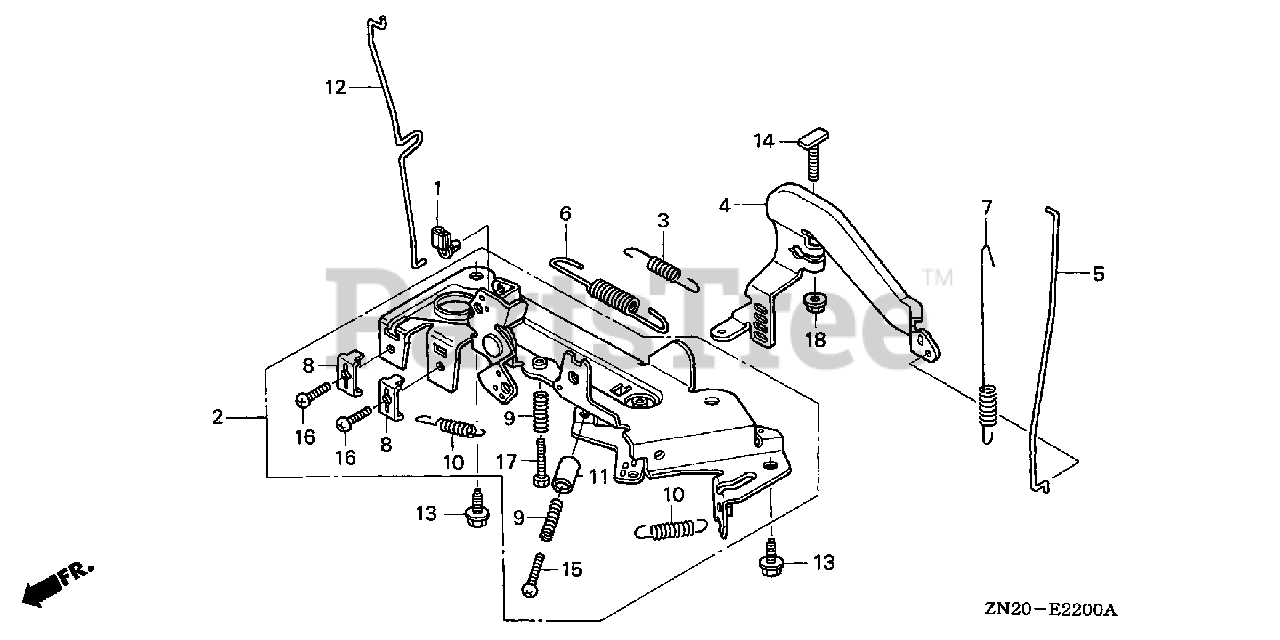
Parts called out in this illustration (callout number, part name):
1	JOINT, ROD
2	CONTROL ASSY.
3	SPRING, STARTER
4	ARM, GOVERNOR
5	ROD, GOVERNOR
6	SPRING, GOVERNOR
7	SPRING, THROTTLE RETURN
8	HOLDER, CABLE
9	SPRING, CONTROL ADJUSTING
10	SPRING, CABLE RETURN
12	ROD, CHOKE CONTROL
13	BOLT, FLANGE (6X14)
14	BOLT, GOVERNOR ARM
15	SCREW, PAN (5X25)
16	BOLT, SLOT (5X16)
17	BOLT, SLOT (5X25)
18	NUT, FLANGE (6MM)
